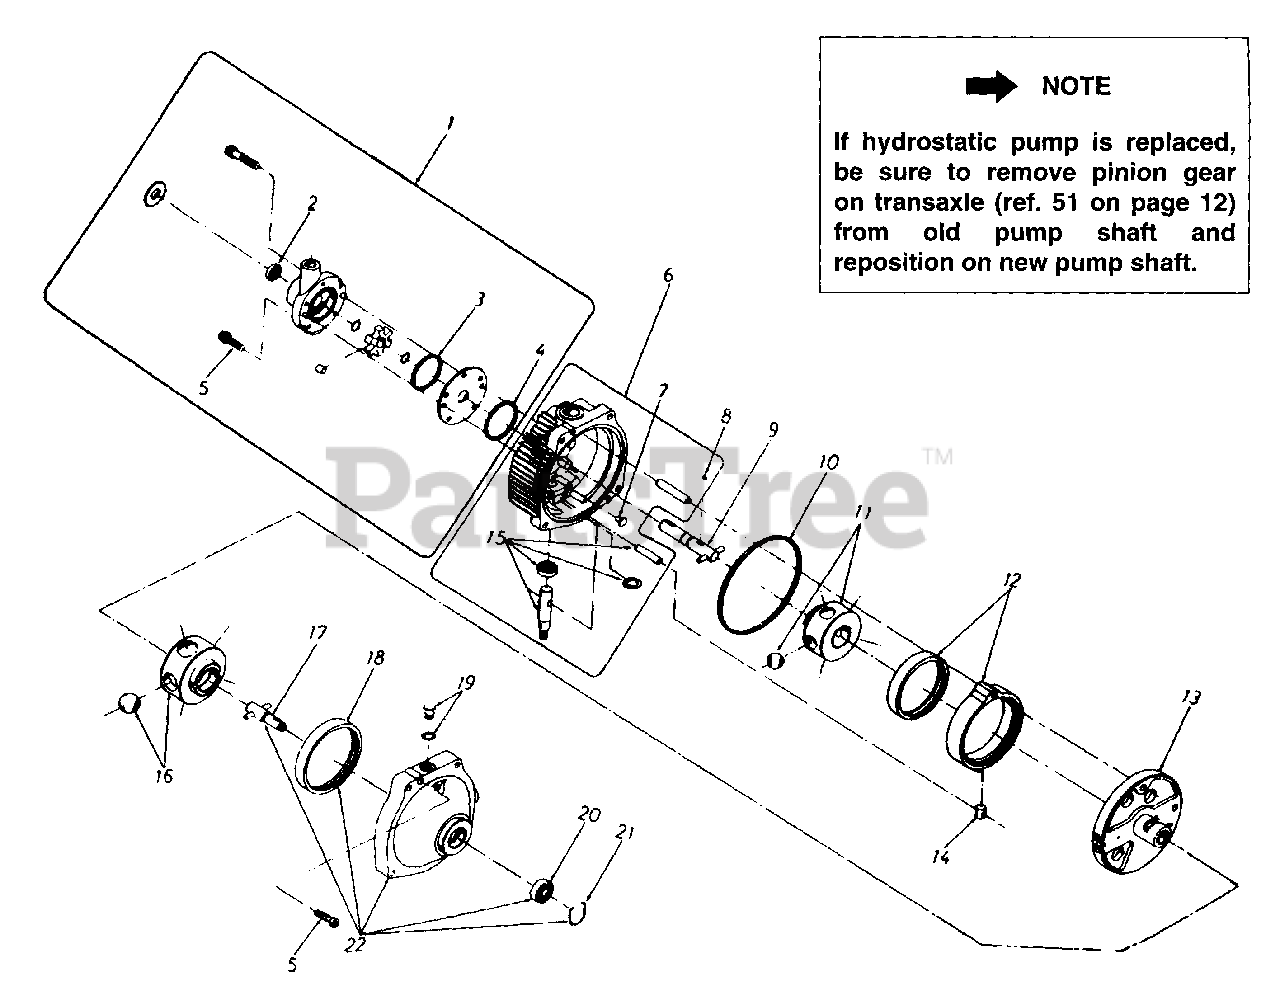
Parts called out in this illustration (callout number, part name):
1	Charge Pump Kit
2	Oil Seal
3	Square Cut Seal Ring .036
4	Square Cut Seal Ring .038
5	Socket Head Cap Screw 5/16-18 x 1.25" Long
6	Cover Subassembly
8	Drive Pin
9	Input Shaft Subassembly
10	Square Cut Seal Ring. 166
11	Pump Rotor Ball Subassembly
12	Cam Ring Subassembly
13	Pintle Subassembly
14	Cam Ring Insert
15	Control Shaft Kit
16	Motor Rotor Ball Subassembly
17	Output Shaft Subassembly
18	Motor Race
19	O-Ring Plug Subassembly
20	Ball Bearing (Output)
21	Retaining Ring
22	Body Subassembly
